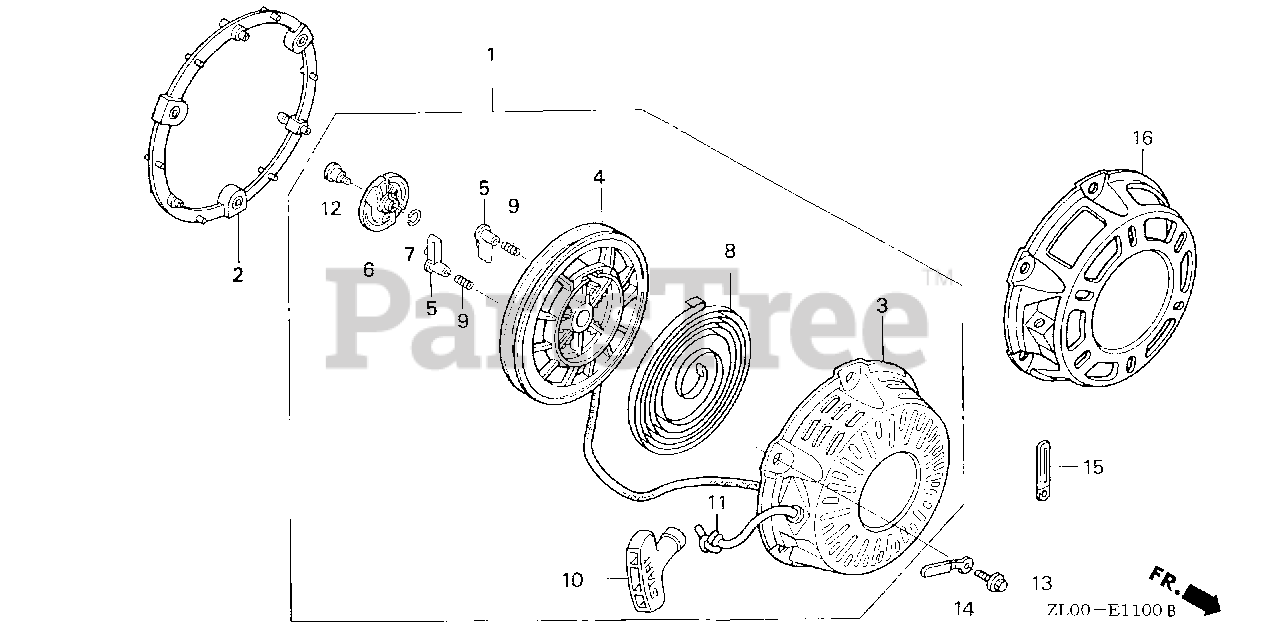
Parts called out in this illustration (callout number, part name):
1	STARTER ASSY., RECOIL *R280* (POWER RED)
1	STARTER ASSY., RECOIL *NH1* (BLACK)
2	SPACER, RECOIL STARTER MOUNTING *NH1* (BLACK)
2	SPACER, RECOIL STARTER MOUNTING *R280R* (POWER RED)
2	SPACER, RECOIL STARTER MOUNTING *R280* (POWER RED)
3	CASE, RECOIL STARTER *R280* (POWER RED)
3	CASE, RECOIL STARTER *NH1* (BLACK)
4	REEL, RECOIL STARTER (NATURAL)
5	RATCHET, STARTER
6	GUIDE, RATCHET
7	SPRING, FRICTION
8	SPRING, RECOIL STARTER
9	SPRING, RETURN
10	GRIP, STARTER
10	KNOB, RECOIL STARTER
11	ROPE, RECOIL STARTER
12	SCREW, SETTING
13	BOLT, FLANGE (6X18)
